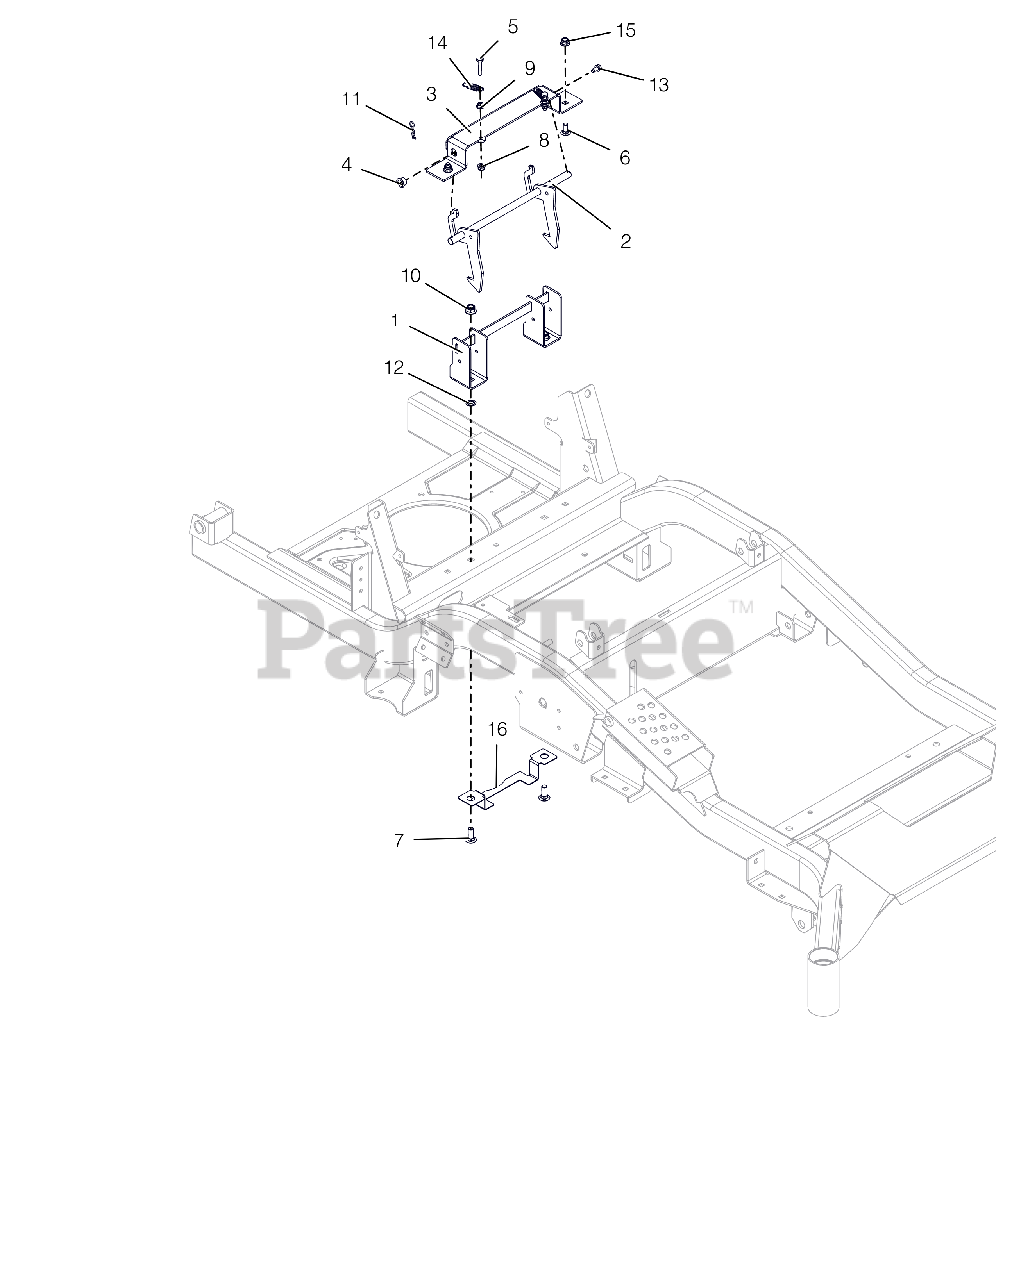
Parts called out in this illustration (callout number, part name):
1	WLDMT, LATCH RECEIVER
2	WLDMT, SEAT LATCH
3	BRKT, SEAT HOOK MTG.
4	BUSHING, POLYLINER-.50 SPLIT
5	@BLT-HEX .25-20X1.25 GR5 YWZC
6	@BLT-RDHDSQNK .31-18X.75 G5YZ
7	@BLT-RDHDSQNK .38-16X1.00 G5YZ
8	@NUT-LK-NYL-FLG .25-20 YWZC
9	@NUT-SPNLK-FLG .25-20 YWZC
10	@NUT-LK-NYL-FLG .38-16 YWZC
11	PIN-HAIR INT .08X.38X1.42 YWZC
12	NUT-PUSH .38 DIA. PAL ZINC
13	SCR-TAP .25-20X.50 HWH TR YWZ
14	SG-TENS .063X.44X1.56
15	@NUT-LK-NYL-FLG .31-18 YWZC
16	GUARD, ELECTRICAL HARNESS
